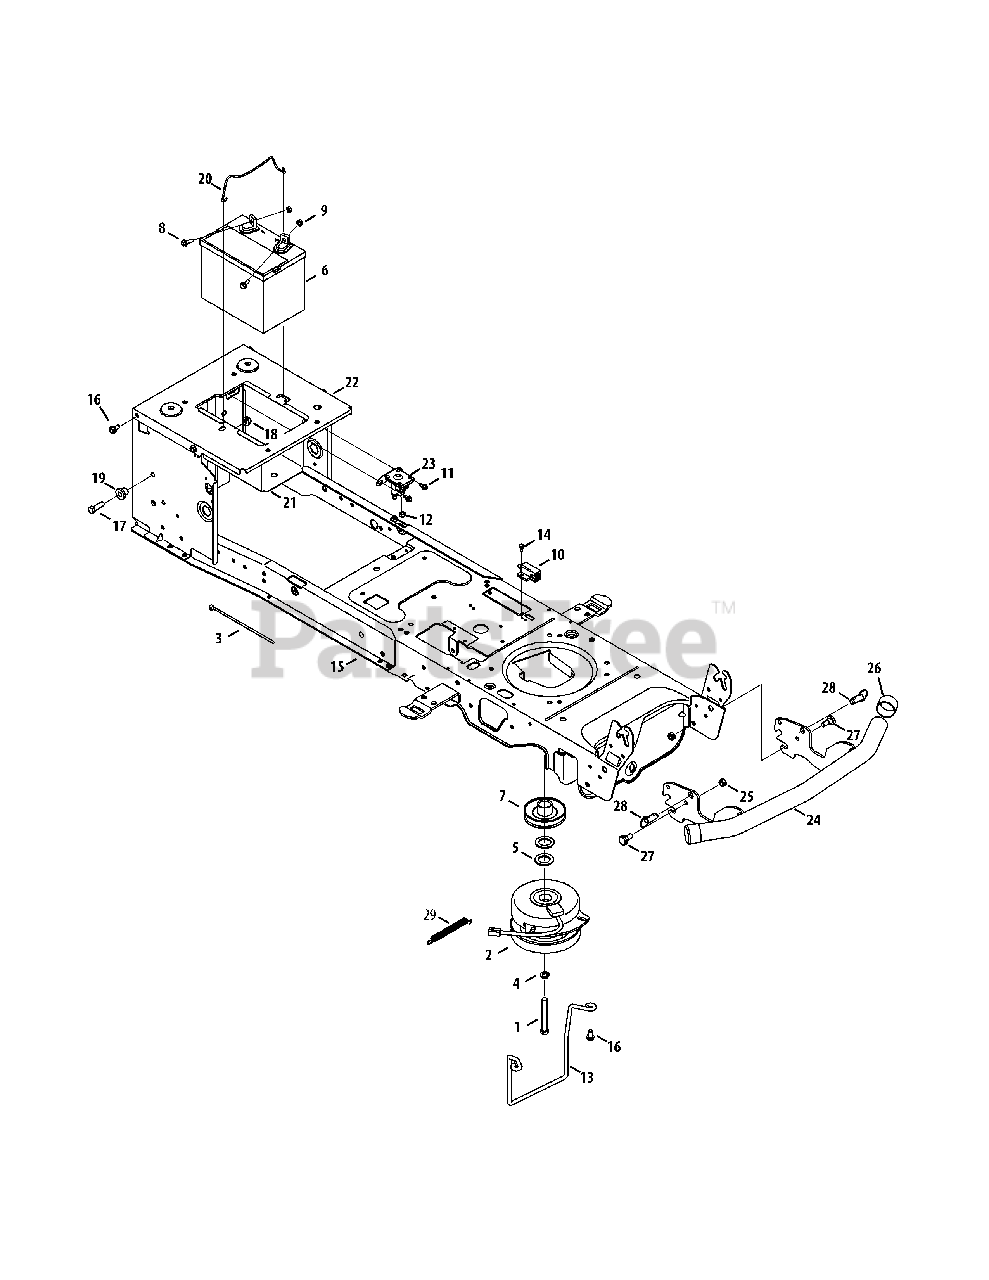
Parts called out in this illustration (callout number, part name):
1	Hex Screw, 7/16-20, 3.50, Gr5, Lock
2	Clutch, Electric PTO 54"
2	Clutch, Electric PTO 50"
3	Cable, Tie, 3/16 X .05 X 7.4
4	Washer, Lock, 7/16 , Regular Duty
5	Washer, Flat, 1.031 X1.620 X.095
7	Engine Pulley, Electric PTO
8	Hex Flange Screw, 1/4-20, .75, Gr5
9	Nut, Sems, 1/4-20
10	Switch, Interlock
11	Screw, Self-tapping, 1/4-20, 0.375
12	Nut, Flange Lock, 1/4-20, Nylon
13	Rod, Keeper
14	Screw, Shoulder, #10-32, .50
15	Frame Assembly, Lower
16	Screw, Self-tapping, 5/16-18, .750
17	Hex Screw, 3/8-16, 1.25, Gr5, Std
18	Nut, Flange Lock, 3/8-16, Nylon
19	Spacer, Shoulder, .38 X 1.0 X .70
20	Rod, Battery
21	Tray, Battery
22	Bracket, Frame, Seat
23	Solenoid, 12V, 100 Amp, 4 term
24	Bumper Assembly, Universal
25	Nut, Hex Lock, 3/8-16, GrB
26	Cap, Bumper
27	Bolt, Shoulder, .496 x .336, 3/8-16
28	Pin, Quick Release, 1/2 Dia x .50
29	Spring, Extn, .56 Dia X 5.52
